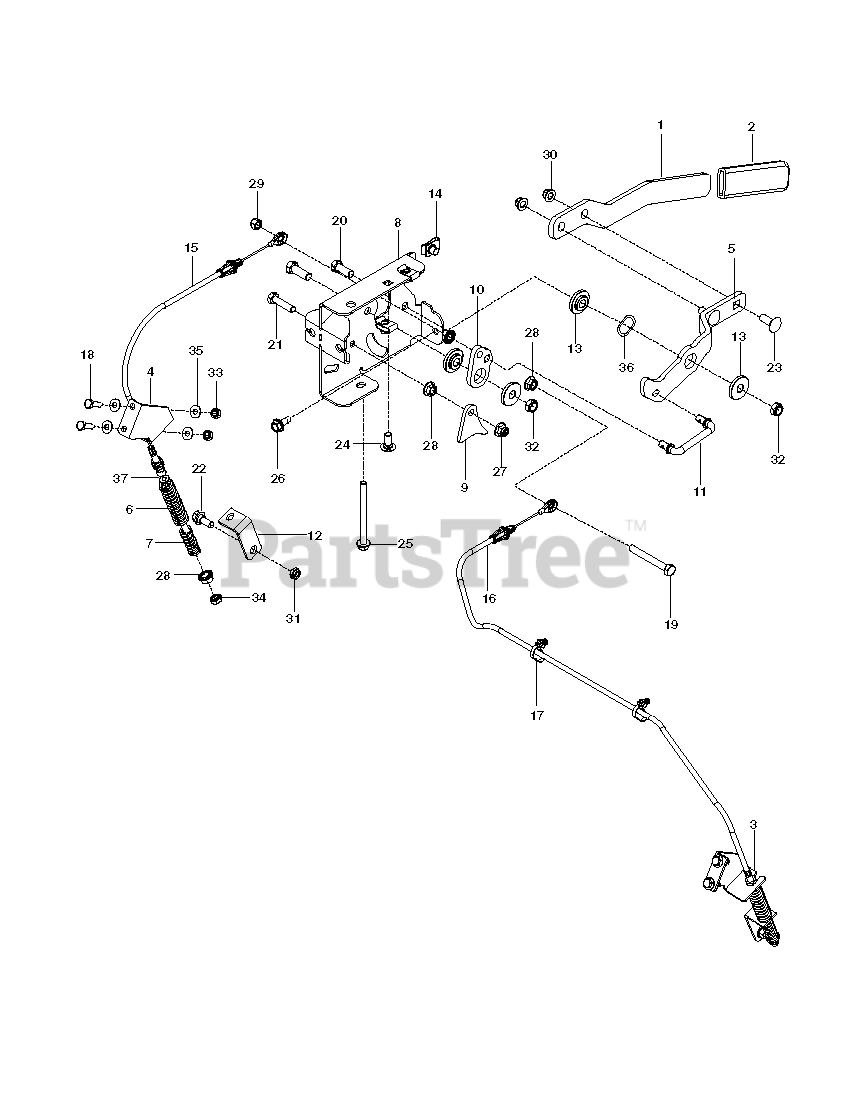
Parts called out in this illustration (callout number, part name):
1	ARM, BRAKE, BLACK
2	GRIP BRAKE HANDLE
3	BRKT, BRAKE RT, BLK
4	BRKT, BRAKE LT, BLK
5	LEVER, BRAKE
6	SPRING, RETURN
7	SPRING, ENGAGEMENT
8	MOUNT, BRAKE WLDMT
9	ACTUATOR, SWITCH
10	BELLCRANK, BRAKE
11	LINKAGE, BRAKE
12	BRKT, BRAKE, BLK
13	BUSHING, BRAKE
14	U-CLIP 5/16-18 NUT RETAINER
15	CABLE, BRAKE, SHORT
16	CABLE, BRAKE, LONG
17	TIE WRAP, 8-3/8", W/CLIP
18	HCS 1/4-20X7/8 GR5
19	HCS 5/16-18 X 2 1/2 TPBLT
20	HCS 3/8C X 1
21	HCS 5/16C X 1
22	BOLT, SHOULDER
23	RHSNB 3/8C X 1
24	BOLT 5/16C X 3/4" CARRIAGE
25	HHFS 5/16-18 X 3 3/4
26	BOLT 5/16-18 X 3/4
27	5/16-18 NYLOC FLANGE NUT
28	NUT 5/16C WHIZ
29	NUT 5/16 NYLOC
30	NUT 3/8-16 HEX FLG NYLOC ZD
31	5/16-18 THIN PROF NY
32	NUT HEX 3/8-16 NYLON, THIN
33	NUT 1/4-20 NYLOC
34	NUT 5/16-18 HEX JAM ZD
35	WASHER 1/4 SAE
36	WASHER, .825 X 1.087, WAVE
37	WASHER 3/8 SAE FLAT
